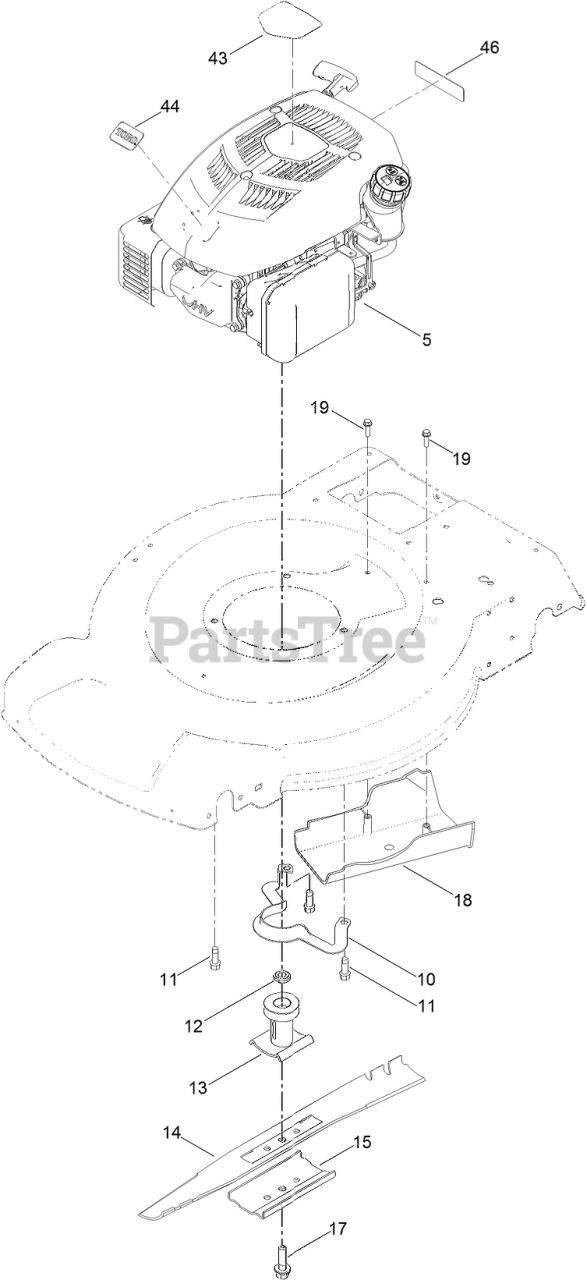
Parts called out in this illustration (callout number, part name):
5	ENGINE-1P65F
10	Guide-Belt
11	SCREW-TAPTITE
12	Spacer-Driver
13	DRIVER-BLADE
14	BLADE-22 INCH
15	SUPPORT-BLADE
17	BOLT-BLADE
18	COVER-BELT
19	SCREW-HWH
43	DECAL-SHROUD
46	DECAL-ARRESTER, SPARK
